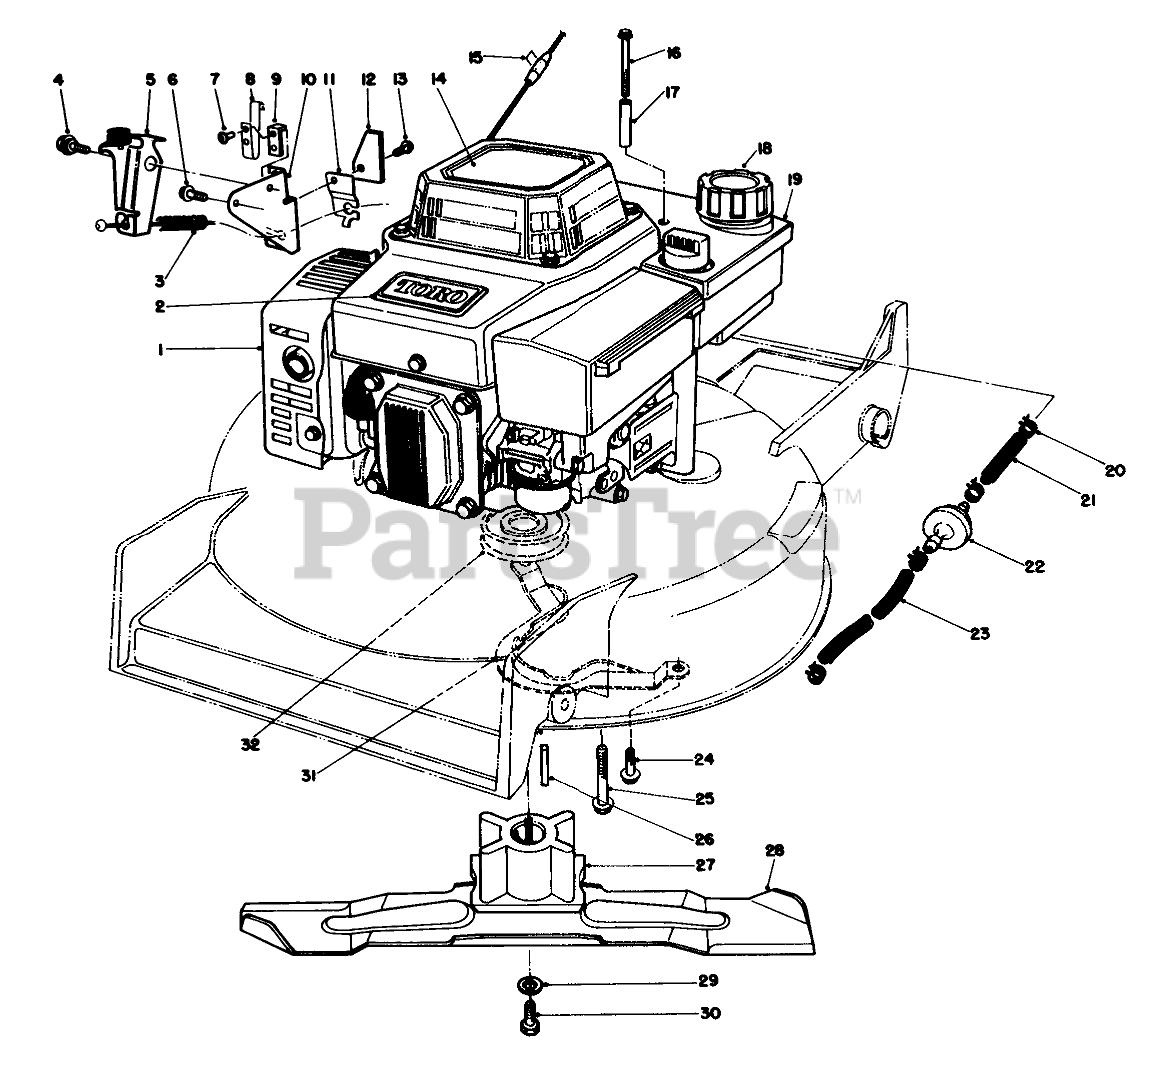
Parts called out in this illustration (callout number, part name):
1	Engine
2	TORO LOGO PLT
3	COMPRESSION SPRING
4	Screw-Shoulder
5	BRAKE PLATE ASM
6	THO FORM SCREW M6 X 1
7	RIVET-PLASTIC
8	STRAP-GROUND
9	Strap-Insulation
10	Plate-Mounting
11	CABLE CLAMP
12	STOP-GROUND STRAP
13	SCREW
14	DECAL - RECOIL GTS
15	Staple
16	THRD FORMING SCREW
17	TUBULAR SPACER
18	GAS CAP ASM
19	TANK ASM
20	CLAMP-FUEL LINE
21	LINE-GAS
22	FILTER-FUEL
23	HOSE-FUEL
24	Screw
25	SCREW-HWHTF
26	KEY-SQUARE
27	Retainer Blade
28	BLADE-21in
29	WASHER-LOCK
30	SCREW-BLADE
31	BELT GUIDE
32	PULLEY-DRIVER
32	PULLEY-DRIVE, ZONE START
